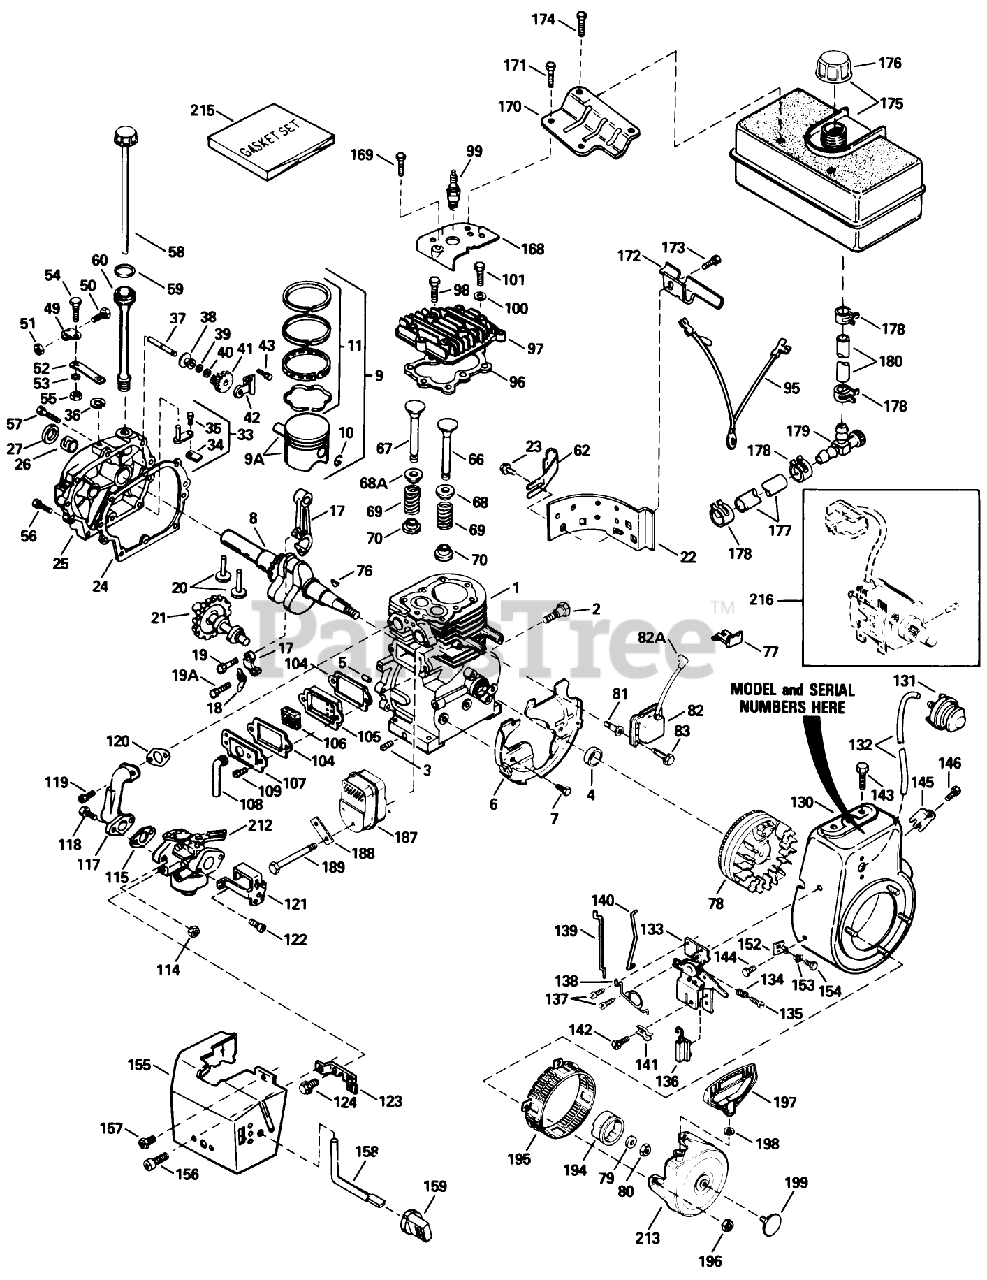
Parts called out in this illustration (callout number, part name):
1	Cylinder Asm (Includes 2, 20, 72)
2	Screw (1/4-20x1/2)
3	Plug-Drain, Oil (SQH 1/4-18)
4	Seal-Oil
5	Pin-Dowel
6	Baffle-Blower Housing
7	Screw (1/4-20x19/32)
8	Crankshaft
9	Piston, Pin Ring Assy.(Std.) (Incl. Ref. #24A, 25 26)
9	Piston, Pin Ring Assy. (.010 oversize) (Incl. Ref. #24A, 25 26)
9	Piston, Pin Ring Assy. (.020 oversize) (Incl. Ref. #24A, 25 26)
9A	Piston Pin Assy. (Std.) (Incl. Ref. #26)
9A	Piston Pin Assy. (.010 oversize) (Incl. Ref. #26)
9A	Piston Pin Assy. (.020 oversize) (Incl. Ref. #26)
11	Ring Set (Std.)
11	Ring Set (.010" OS)
11	Ring Set (.020" OS)
17	Rod Assy., Connecting (Incl. Ref. #28 28A)
18	Dipper-Oil
19	Bolt-Rod
19A	Bolt-Rod
20	Lifter-Valve
21	Camshaft (MCR)
22	Extension-Housing, Blower
23	Screw
24	Cylinder Cover Gasket
25	Cover-Cylinder (Includes 71, 75, 80)
26	2025A77 WIZARD ROTA
27	Seal-Oil
33	Rod, Governor (Incl. Nos.62 63)
34	Yoke-Governor
35	Screw (6-40x5/16)
36	Ring-Retaining
37	Shaft-Governor
38	Spool-Governor
39	Washer
40	Ring-Retaining
41	Gear Assy., Governor (Incl. Ref. #45)
42	Bracket-Gear, Governor
43	Screw (10-24x1/2)
49	Clamp-Lever, Governor
50	Screw
51	Nut-Lock
52	Lever-Governor
53	Washer-Lock
54	Screw
55	Nut-Lock
56	Screw (1/4-20x1-11/16)
57	Screw (1/4-20x1-3/16)
58	Dipstick
59	O-Ring
60	Tube-Fill, Oil
62	Clip-Tube, Fill
66	Valve, Exhaust (Standard)(Incl. No. 9)
66	Valve, Exhaust (1/32" oversize)(Incl. No. 9)
67	Valve, Intake (Std.) (Incl. Ref. #58)
67	Valve, Intake (1/32" oversize) (Incl. Ref. #58)
68	Cap-Spring, Valve
68A	Seal-Intake Valve
69	Spring-Valve
70	Keeper-Spring, Valve
76	Key-Flywheel
77	Clip-Wire
78	Flywheel (W/Ring Gear)
79	Washer-Belleville
80	Nut-Flywheel
82	Solid State ASM
82A	Cover-Spark Plug
83	Screw
95	Ground Wire
96	Gasket-Cylinder Head
97	Head Cylinder
98	Screw (5/16-18x1-1/2)
99	Spark Plug-Resistor (R J19 L M)
100	Washer-Flat
101	Screw (5/16-18x1-25/32)
104	Gasket-Cover, Valve
105	Body-Breather
106	Element-Breather
107	Cover-Valve
108	Tube-Breather
109	Screw
114	Nut and Lock Washer (1/4-28)
115	Gasket-Carburetor To Intake Pipe
117	Pipe-Intake
118	Screw (1/4-28x1)
119	Screw (T-30, 5/16-18x1-3/32)
120	Gasket-Pipe, Intake
121	Bracket-Choke
122	Screw (10-32 x 1/2)
123	Bracket-Carburetor
124	Screw (8-32x27/64)
130	Housing-Blower
131	Primer-Asm
132	Line-Primer
133	Control Assy., Remote Speed (Incl. Ref. #90 thru 93)
134	Spring-Compression
135	Screw
136	Terminal
137	Screw (10-32 x 1/2)
138	Spring-Throttle
139	Link-Governor
140	Link-Throttle
141	Conduit
142	Screw (10-32 x 3/8)
143	Screw (5/16-18x3/4)
144	Screw
145	Screw
146	Screw (8-32 x 3/8)
152	Bracket
153	Grommet
154	Screw (8-32 x 3/8)
155	Cover-Carburetor
156	Screw (10-32 x 3/8)
157	Screw (10-32x1/2)
158	Rod-Choke
159	Knob-Control
168	Cover-Cylinder Head
169	Screw (1/2-20x5/8)
170	Bracket-Tank, Fuel (Black)
171	Screw
172	Bracket-Tank, Fuel
173	Screw (1/4-20x19/32)
174	Screw (1/4-15x7/8)
175	Tank-Fuel (Includes 292, 301)
176	Cap-Fuel
177	Line-Fuel
178	Clamp-Line, Fuel
179	Valve-Shut Off
180	Line-Fuel (8.62)
187	Muffler
188	62513 SNWTHWR W/284
189	Screw
194	Cup-Starter
195	Screen-Starter
196	Nut and Lock Washer (1/4-28)
197	Handle-Starter, Mitten Grip
198	Washer
199	Plug Starter
212	Carburetor (Incl. Ref. #184)
213	Starter-Rewind
215	Gasket Set (Incl. items marked *)
216	Electric Starter Kit No. 33329C (Optional) Order as an Accessory.
